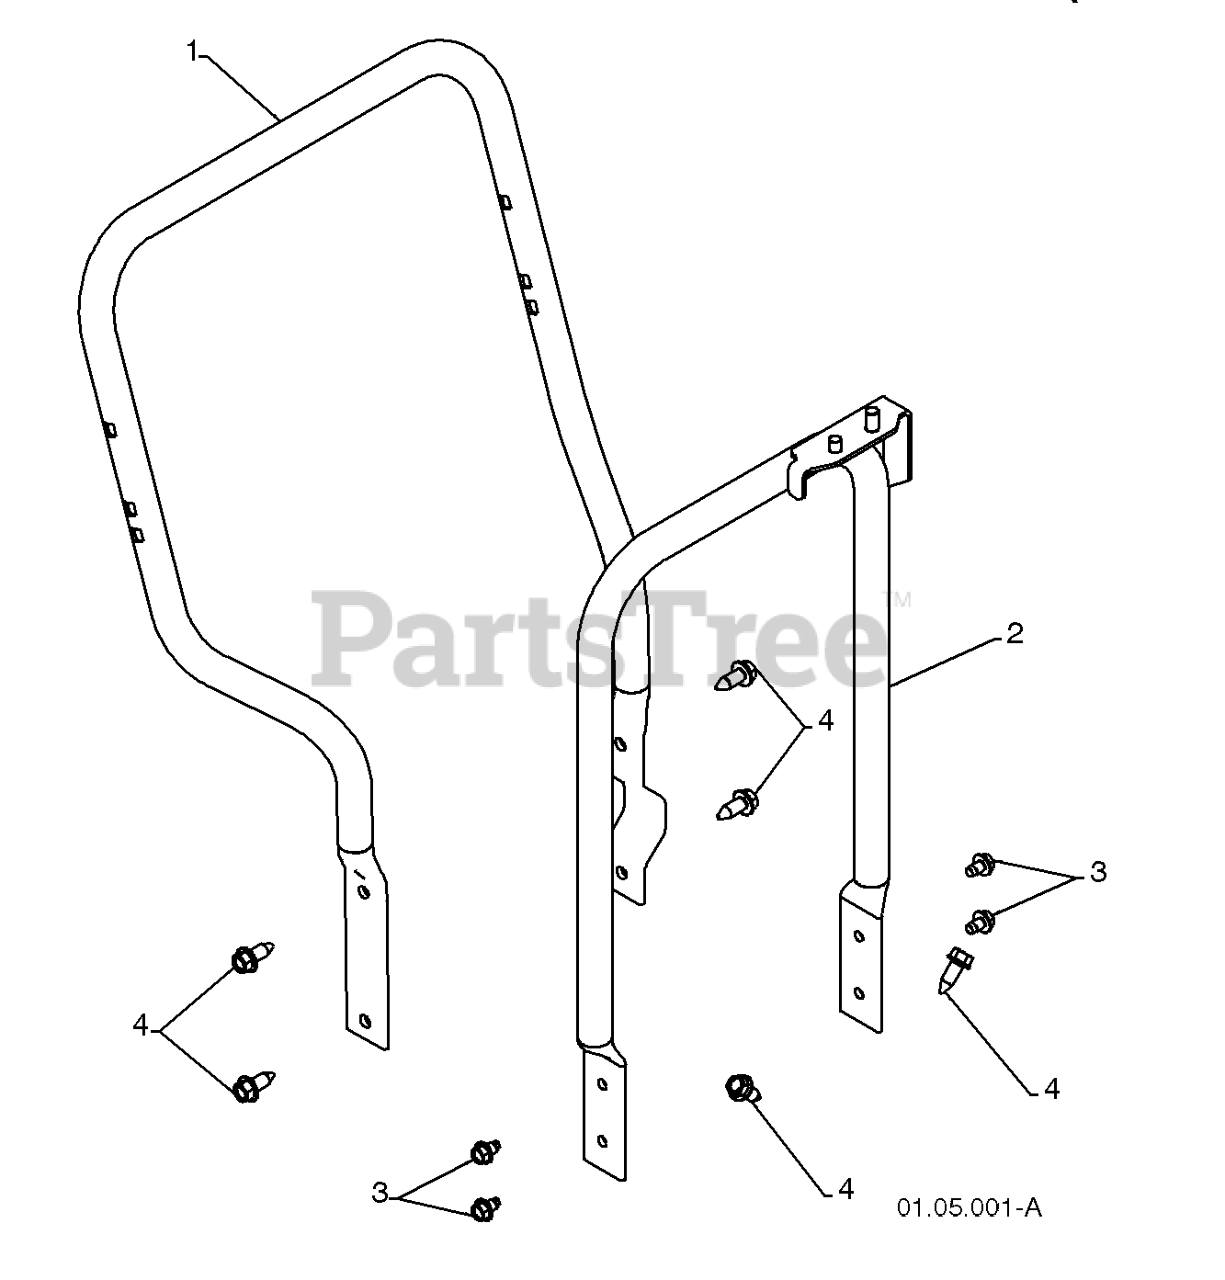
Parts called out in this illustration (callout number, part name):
1	TUBE.LOWER.HANDLE.SNOW.BLACK
2	SUPPORT, PIVOT
3	BOLT 5/16-18 X .500
4	SCREW 3/8-16X1
